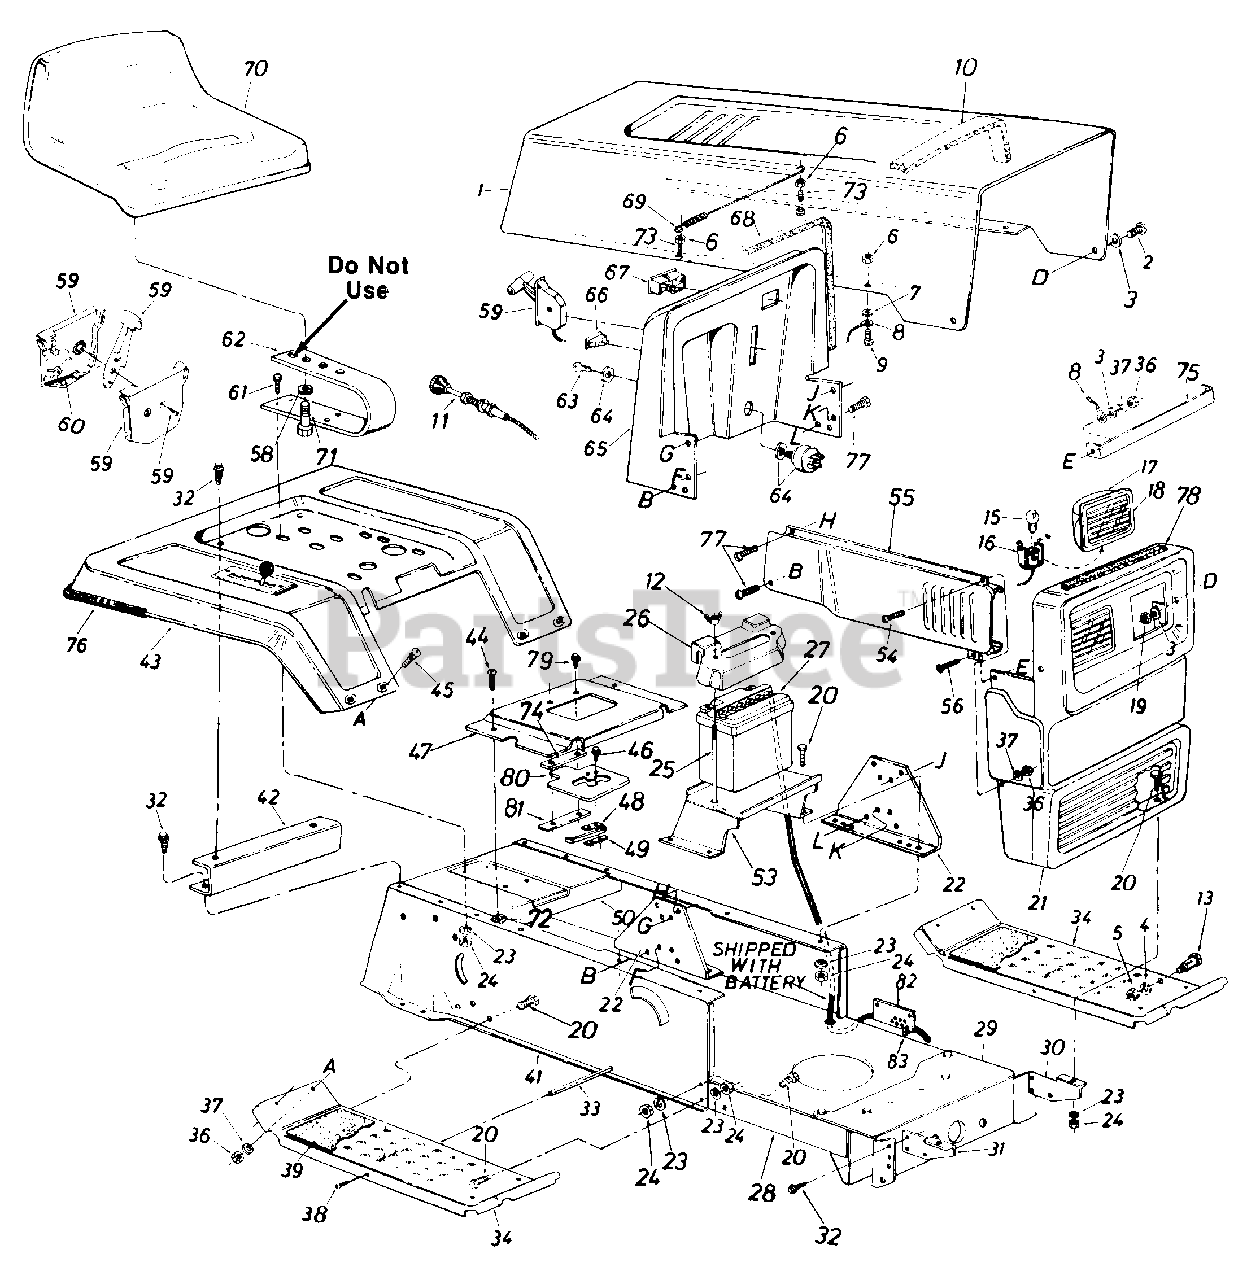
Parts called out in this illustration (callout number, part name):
1	Hood
2	Hex Scr. 1/4-20 x .62" Lg.
3	Fl-Wash. .296" I.D. x .62" O.D.
4	L-Wash. 3/8 I.D.
5	Hex Nut 3/8-16 Thd.
6	Hex Sems Nut #10-24 Thd.
7	Fl-Wash. .203" I.D. x .41" O.D. x .040
8	Hood Stop
9	Truss Hd. Scr. #10-24 x 1/2" Lg.
10	PVC Foam
11	Choke Control
12	Wing Nut 1/4-20 Thd. Plastic
13	Shld. Bolt .50" Dia. x .84
15	Lamp
16	Socket
17	Headlight Housing
18	Lens
19	Hex L-Nut 1/4-20 Thd.
20	Hex Bolt 5/16-18 x .75" Lg.
21	Grille
22	Dash Support Bracket
23	L-Wash. 5/16" I.D.
24	Hex Nut 5/16-18 Thd.
25	Battery Hold Down Rod
26	Battery Cover
27	12 Volt Battery
28	Lower Frame
29	Front Pivot Brk't.
30	Grille Mount Brk't. L.H.
33	Running Board Rod
34	Running Board
36	Hex Nut 1/4-20 Thd.
37	L-Wash. 1/4" I.D.
38	Truss Mach. Scr. 5/16-18 x .75" Lg.
39	Foot Pad
41	R.H. Side Frame
42	Fender Mount Brace
43	Rear Fender
44	Truss Mach. Tap Scr. #10 x .50" Lg.
45	Carriage Bolt 1/4-20 x .50" Lg.*
46	Truss Hd. Scr. #10-24 x .50" Lg.*
47	Transmission Panel
48	Reverse Safety Switch
49	Insulator Nut Plate
50	Hitch Plate
53	Battery Bracket
54	Truss Hd. Scr. 1/4-20 x .75" Lg.*
55	Side Cover R.H.
56	Truss Mach. Scr. 1/4-20 x .50" Lg.
58	L-Wash. 1/2" I.D.
59	Throttle Control Box Ass'y.
60	Throttle Control Wire
61	Hex Bolt 5/16-18 x 1.00" Lg.
62	Seat Spring 5.5" High
63	Ignition Key
64	Ignition Switch
65	Dash Panel
66	Light Switch
67	Ammeter
68	Trim Strip 27"
69	Hood Spring
70	Seat Ass'y.
71	Hex Bolt 1/2-13 x 1.0" Lg.
72	Speed Nut #10Z
73	Hex Scr. #10-24 x 1.0" Lg.
74	Spacer Plate
75	Tie Strap Grille/Side Panel
76	Trim Strip 81"
77	Hex Wash. Hd. Tap Scr. 1/4 x .75" Lg.
78	Foam Strip 3/8 x 1 x 14" Lg.
79	Truss Mach. Scr. 1/4-20 x .75" Lg.
80	Gear Selection Plate
81	Clamping Plate
82	Brake Cable Brk't.
83	Cable Tie
